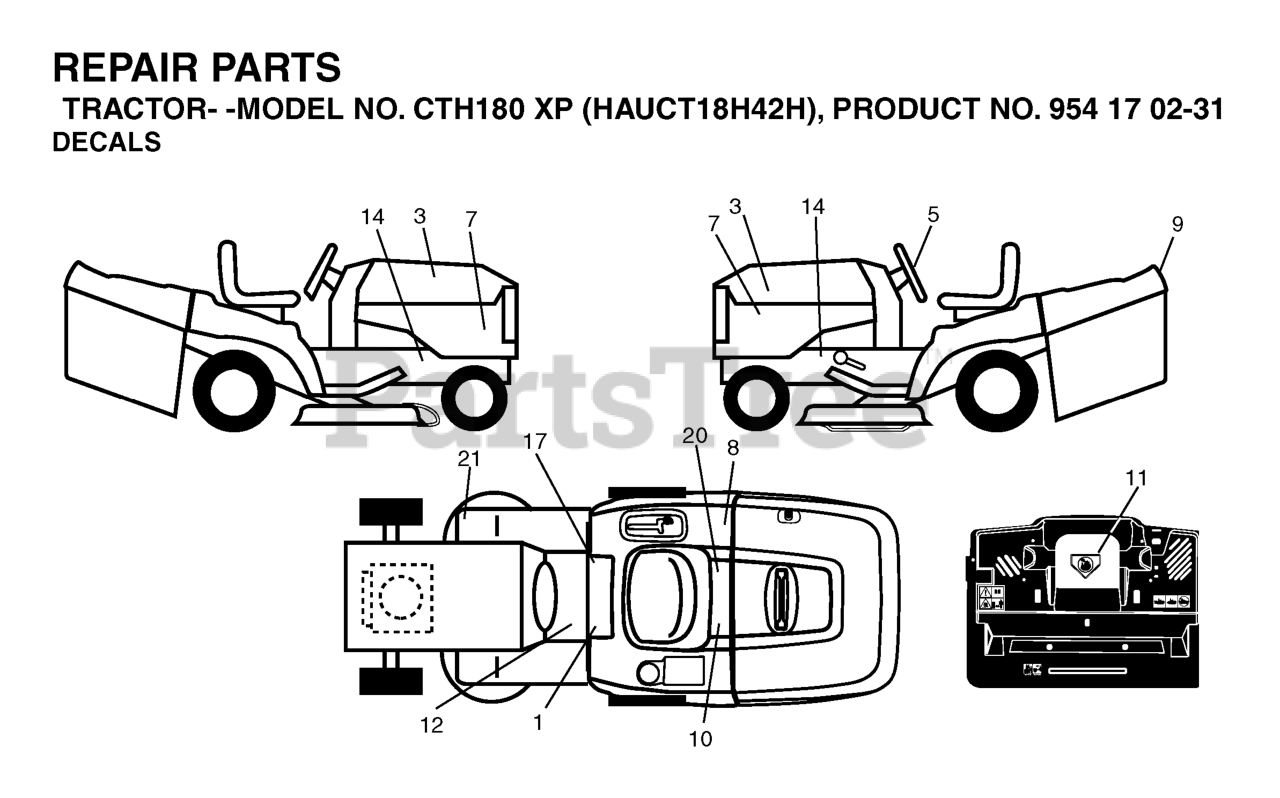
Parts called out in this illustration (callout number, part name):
1	DECAL READ OWNER'S MAN SYMS
3	DECAL.HOOD.HUSQVARNA.INTERNATI
5	DECAL.STEERING.HUSQ.BLUE
8	DECAL
10	DECAL BTRY SYMBOLS
11	DECAL.INTERNATIONL.CUTFINGER
12	DECAL
17	DECAL PARK BRAKE
20	DECAL.BYPASS.FENDER.CRD.LT.YT
